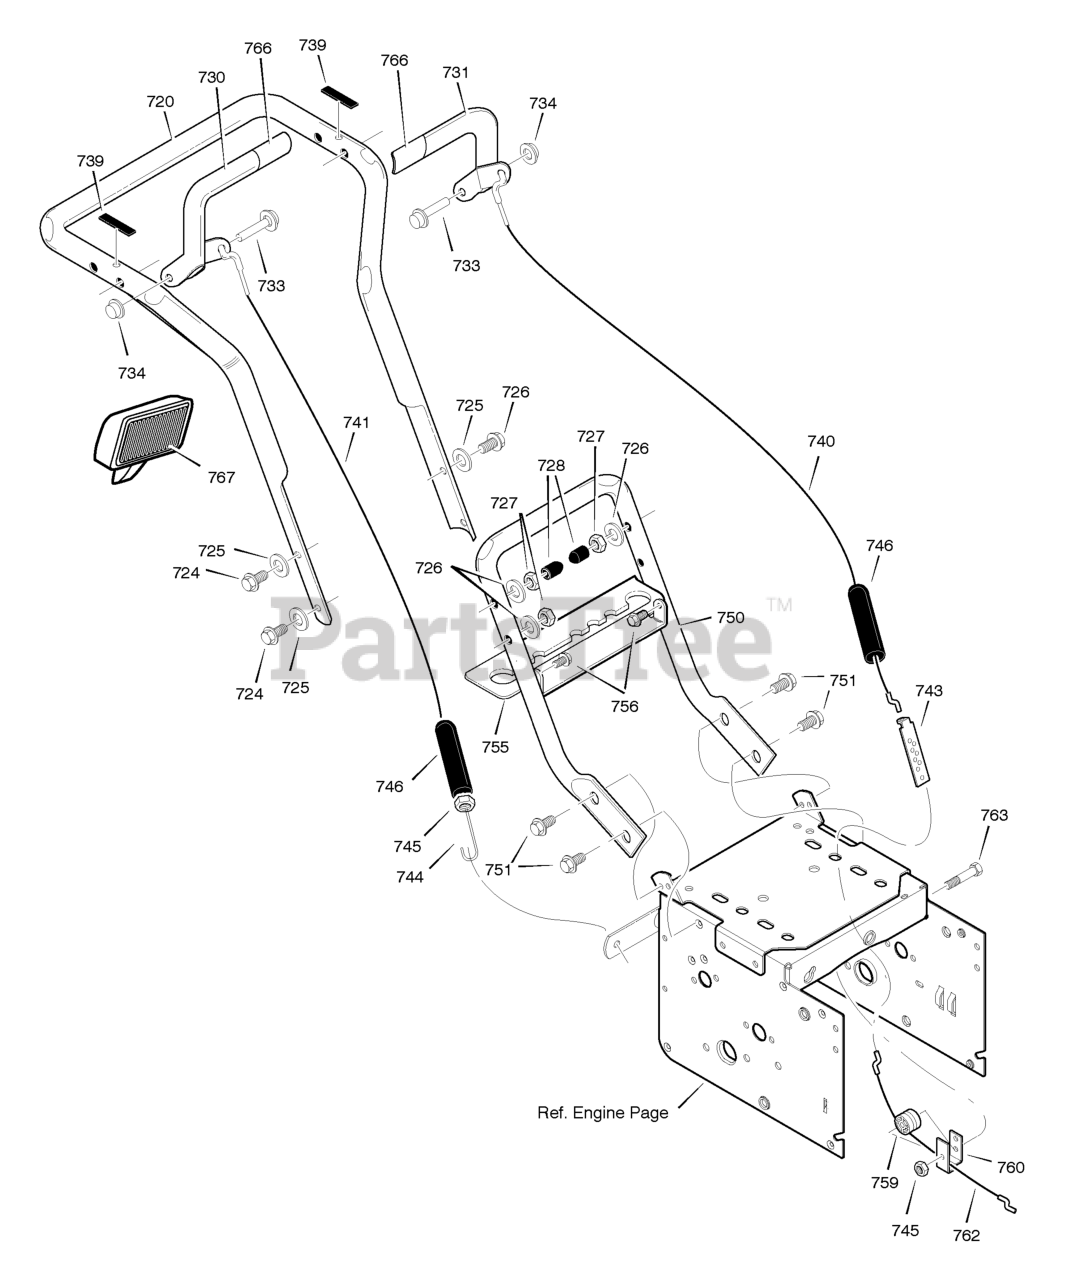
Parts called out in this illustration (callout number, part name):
720	HANDLE, UPPER
724	SCREW, 5/16-18 x 2.75
725	WASHER, FLAT
726	WASHER, SPTLK .31X.58X.08
727	NUT, 5/16-18 REGHEX
728	STOP, RED PLASTIC
730	CLUTCH HANDLE, RIGHT
731	CLUTCH HANDLE, LEFT
733	PIN, PIVOT CLUTCH
734	NUT, PUSH ON CAP
739	BUMPER, RECTANGLE
740	CABLE, CLUTCH 28.44L
741	CABLE, AUGER CLUTCH
743	BRACKET, CABLE ADJUSTER
744	SPRING, AUGER CLUTCH
745	NUT, 1/4-20
746	BOOT, CLUTCH SPRING
750	HANDLE, LOWER
751	SCREW, TAP 5/16-18 X .75
755	BRKT, GEAR SELECTOR
756	SCREW, 1/4-20 X 0.63
759	SPOOL-CABLE, AUGRT CLUTCH
760	BRACKET, CABLE SPOOL YZ
762	CABLE, LOWER DRIVE 12"
763	BOLT, HEX 1/4-20 X 1.50
767	HEADLIGHT
